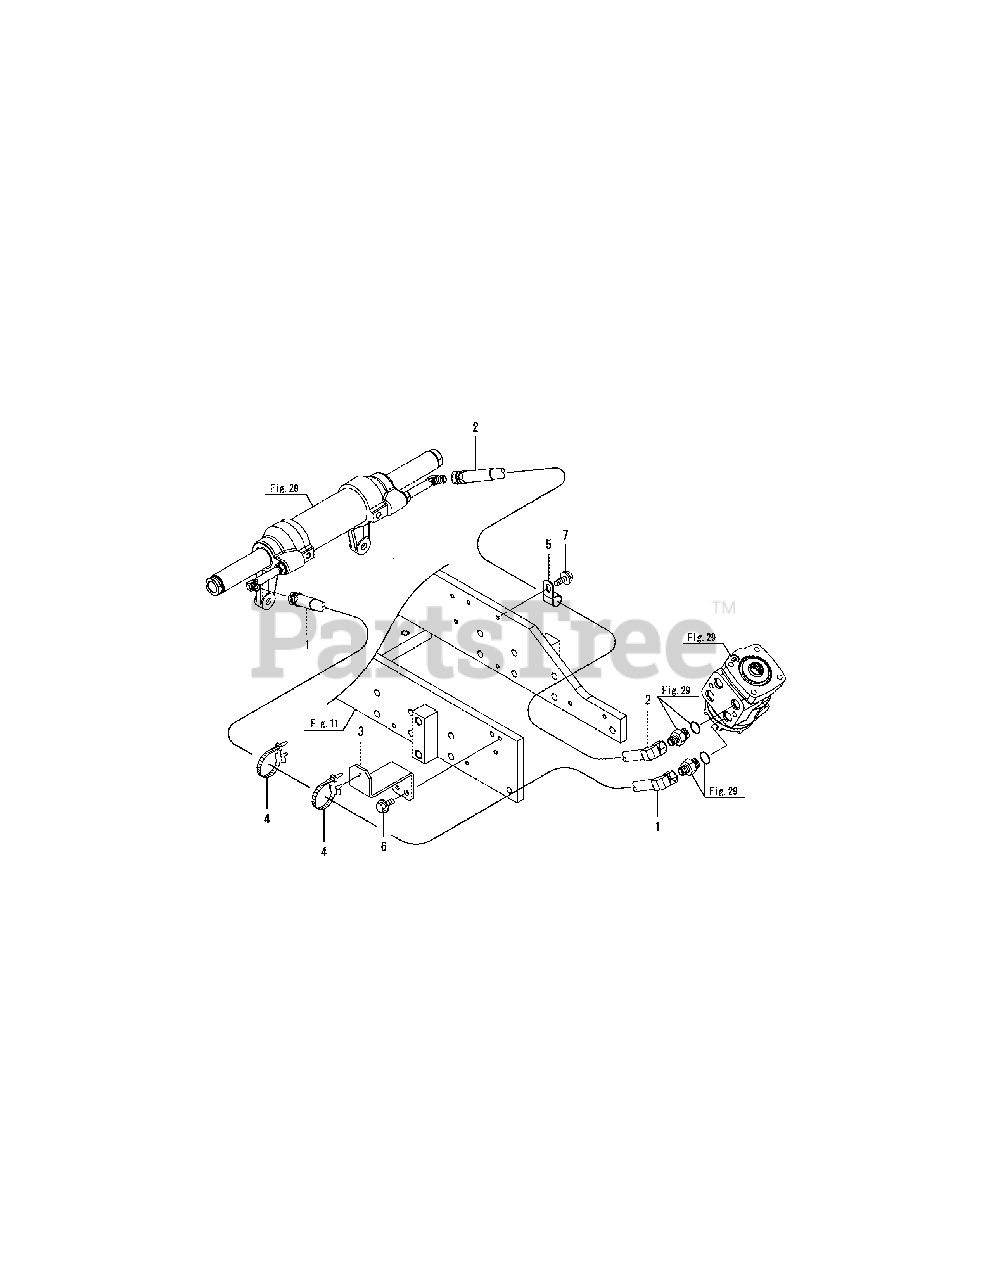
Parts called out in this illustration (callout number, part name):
1	HOSE, CYLINDER
2	HOSE, CYLINDER
5	CLIP 18,HARNESS
6	BOLT M 8X 16 PLATED
7	BOLT M 8X 16 PLATED
